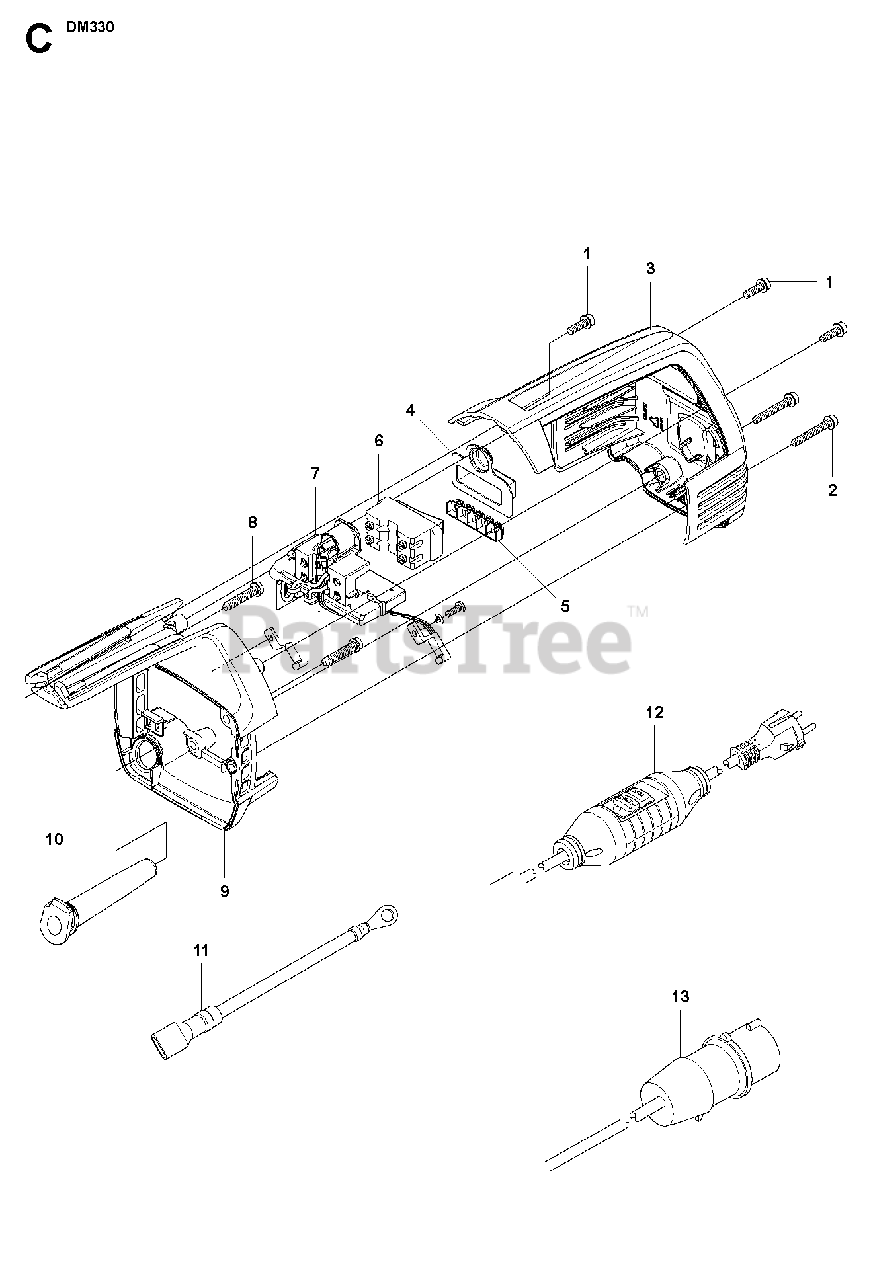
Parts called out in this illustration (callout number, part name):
1	SCREW IHSCFM
2	SCREW IHSCFM
12A	CABLE230V incl PRCD 10mV, EU
12B	CABLE230V incl PRCD 10mV, AU
